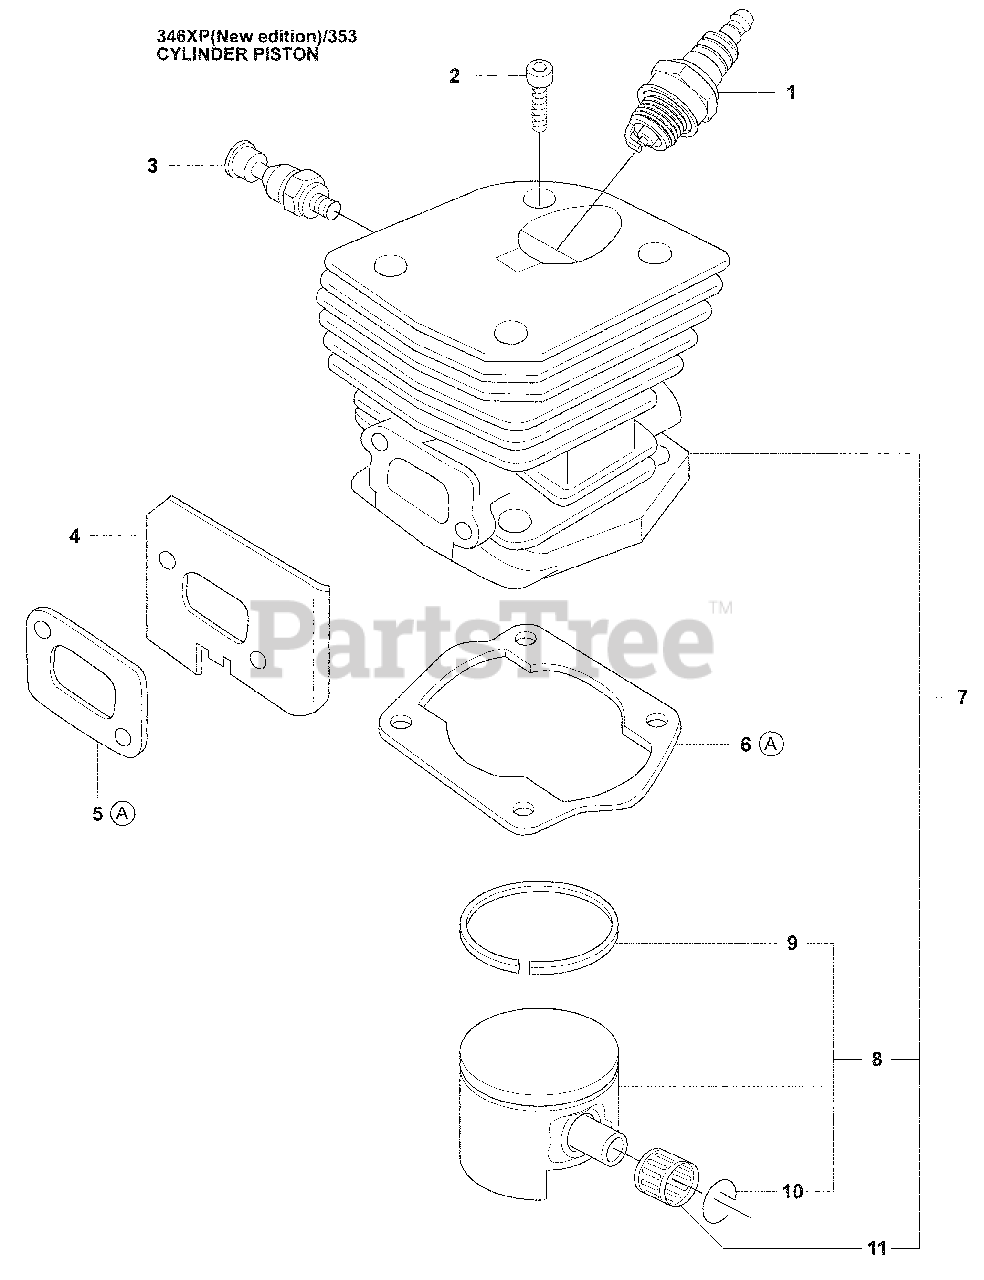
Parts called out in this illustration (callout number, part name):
1	Solid Spark Plug, BPMR7A
2	Screw, MC6S 5 X 25
3	Decompression Valve
5	Muffler Gasket
7	Cylinder Assembly
7	Cylinder
8	Piston
9	Piston Ring
10	Locking Ring
11	Support Bushing
12	Gasket Set
